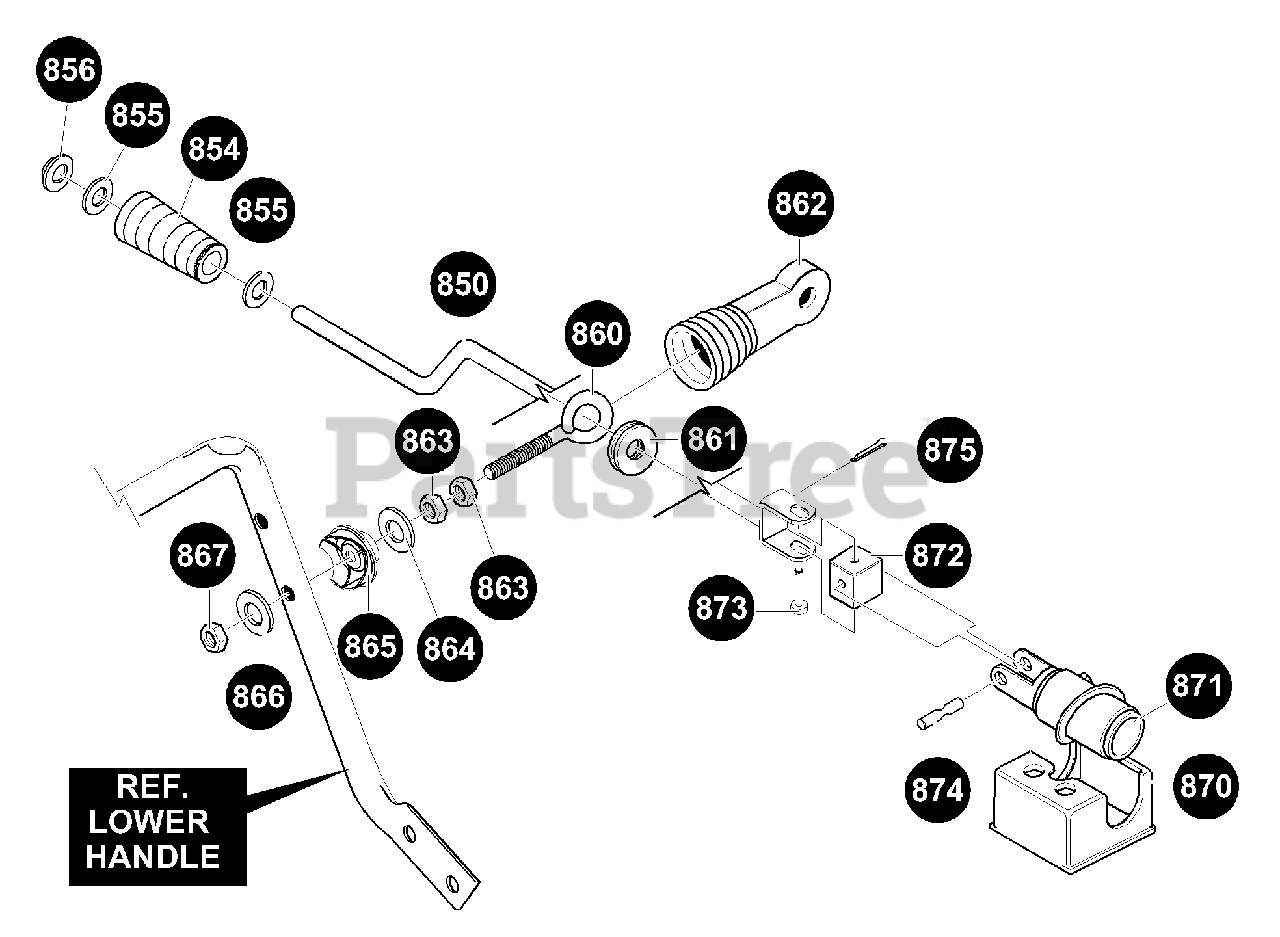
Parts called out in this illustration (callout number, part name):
850	CRANK, ASSY
854	HANDLE, CHUTE CRANK
855	FLATWASHER .39X.70X.05
856	RETAINING RING
861	GROMMET, EYE BOLT
862	BOOT, EYE BOLT
863	NUT, 3/8-16
864	WASHER, FLAT .406X .81X.065
865	BOOT, ADAPTER
866	WASHER, FLAT .406X .81X.065
867	NUT, 3/8-16
870	BRKT, WORM
871	WORM, GEAR CHUTE
872	BLOCK, UNIV PIV
873	PIN, CLEVIS
874	PIN, UNIV JOINT
875	PIN, COTTER
